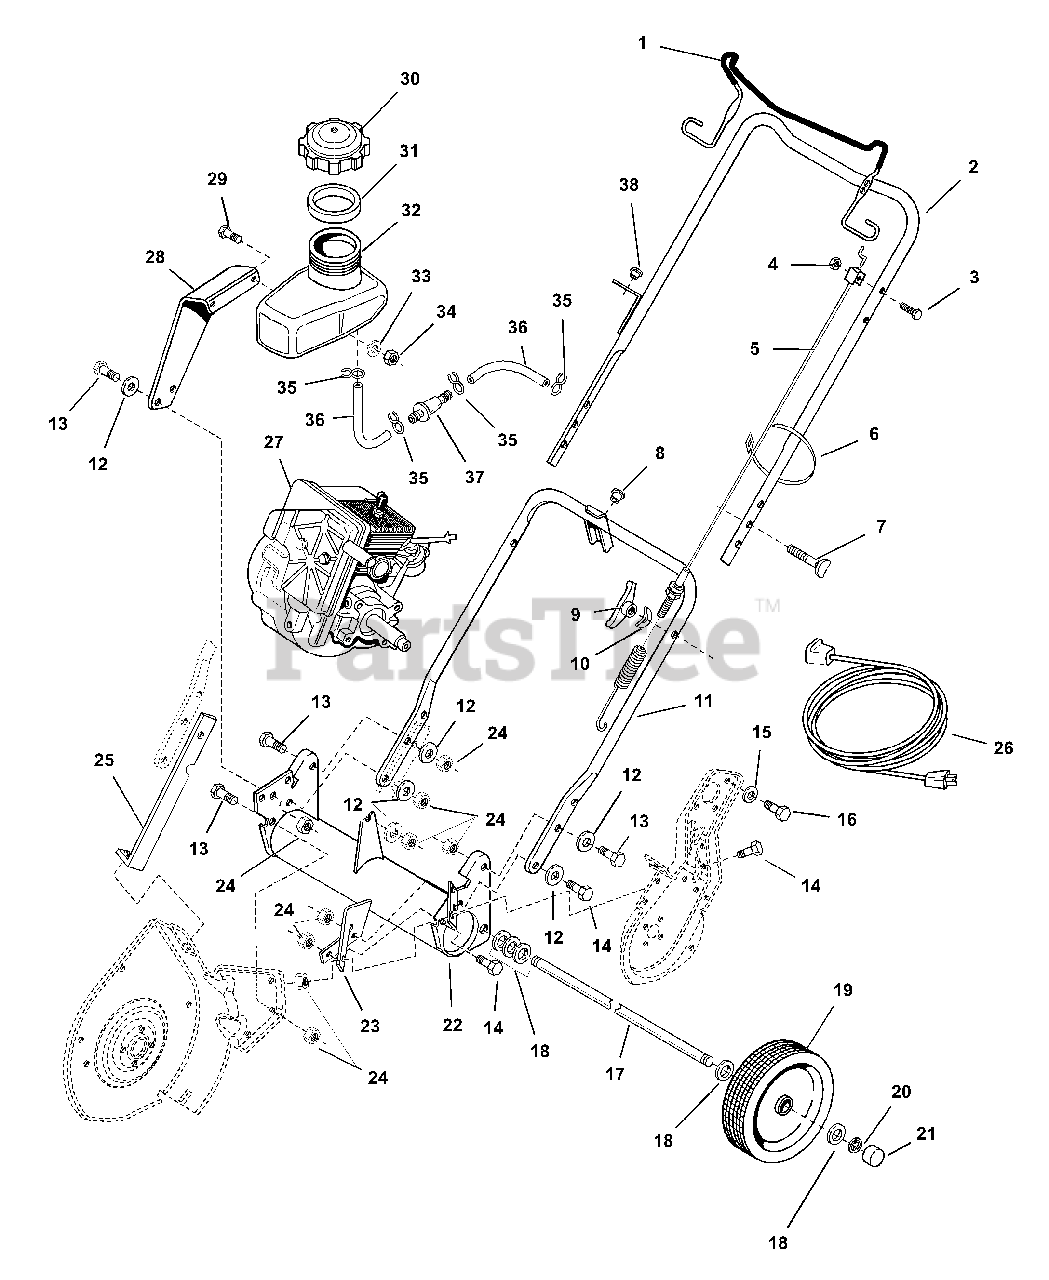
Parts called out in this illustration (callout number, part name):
1	AUGER CONTROL BAIL, Coated
2	UPPER HANDLE ASSY.
3	CAPSCREW, Hex Hd., 1/4-20 x 1-1/4
4	NUT,Hex Centerlock, 1/4-20
5	CABLE, Auger Control
7	BOLT, Rd. Hd., 5/16-18 x 1-3/4
8	SNAP BUSHING, 3/8
9	KNOB, Wing
10	WASHER, Curved, 5/16
11	LOWER HANDLE ASSY.
12	WASHER 3/4 OD.
13	CAPSCREW, Hex Hd., 5/16-18 x 3/4
14	CAPSCREW, Hex Hd., 5/16-18 x 1
15	LOCKWASHER, 5/16
16	CAPSCREW, Hex Hd., 5/16-18 x 3/4
17	SHAFT, Axle
18	WASHER
19	SEMI-PNEUMATIC TIRE
20	RING, Retainer, Ext., #37
21	CAP,Hub
22	TUBE FRAME ASSY.
23	BRACKET, Reinforcement
24	NUT, Hex Lk., Esna, 5/16-18
26	CORD, Extension (Electric Start Models)
27	ENGINE, Manual Start, Model
27	ENGINE, Electric Start
28	TANK BRACKET
29	CAPSCREW, Hex Hd., 1/4-20 x 3/4
31	GASKET, Foam Ring
32	FUEL TANK
33	WASHER
34	NUT, Hex Lk. Esna, 1/4-20
35	CLAMP, Wire Form
36	HOSE, Fuel, 5-1/2 long
37	FILTER, Gas
38	SNAP BUSHING, 1/4
